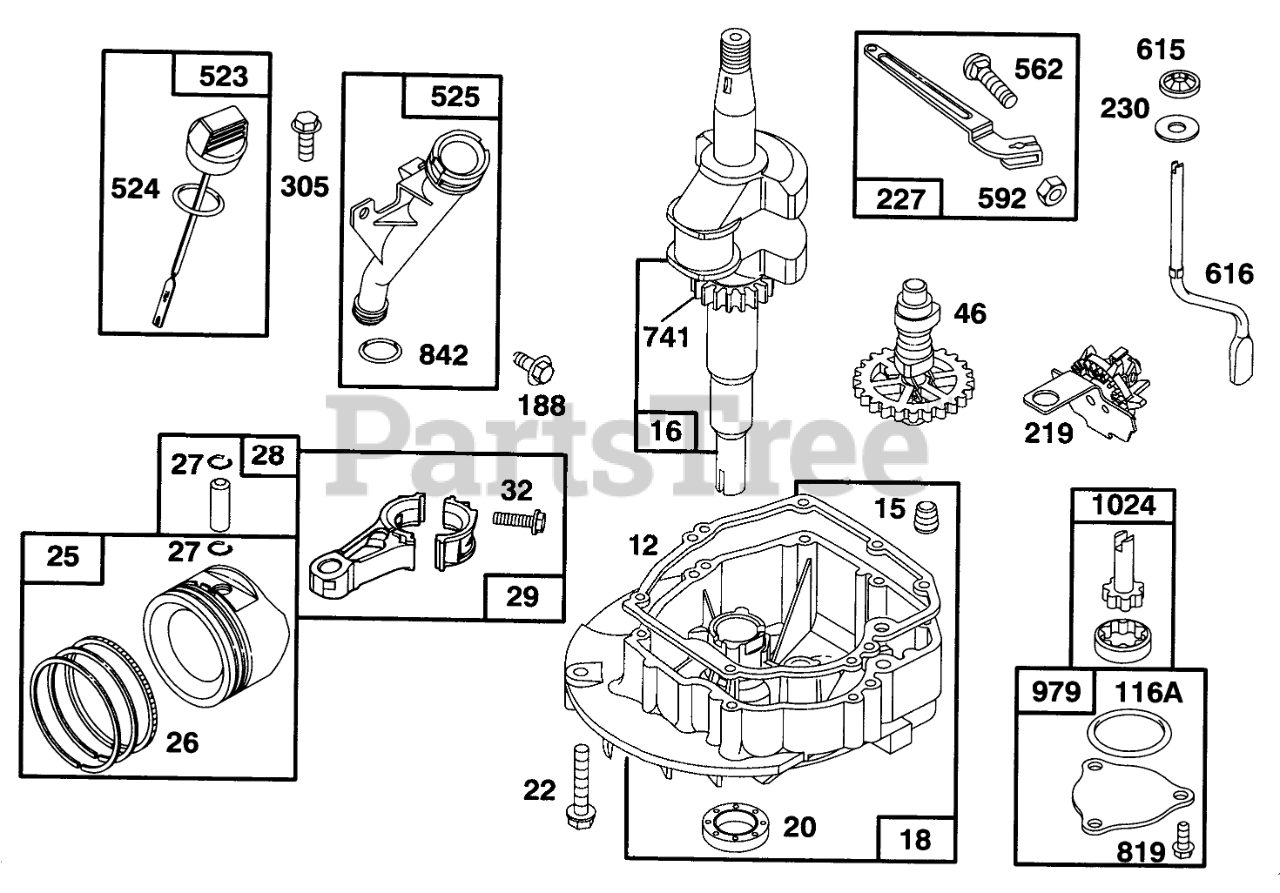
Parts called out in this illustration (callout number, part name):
12	ENGINE BASE GASKET
15	PLUG - PIPE
16	Crankshaft
18	ENGINE SUMP
20	SEAL-OIL
22	SCREW - ENGINE BASE
25	STD PISTON ASSEMBLY
26	STD RING SET
27	PISTON PIN LOCK
28	PIN ASM - PISTON
29	CONNECTING ROD
32	SCREW - CONNECTING ROD
46	CAM GEAR
116A	O RING SEAL
188	Screw-Cap
219	GOVERNOR/OIL SLINGER
227	GOVERNOR LEVER ASSEMBLY
230	WASHER
305	SCREW - HEX HEAD
523	DIPSTICK-OIL
524	O-RING
525	OIL FILLER TUBE
562	GOVERNOR LEVER BOLT
592	HEX NUT
615	FASTENER
616	GOVERNOR CRANK
741	TIMING GEAR
819	Screw-Cap
842	O-RING
979	OIL PUMP COVER
1024	OIL PUMP
